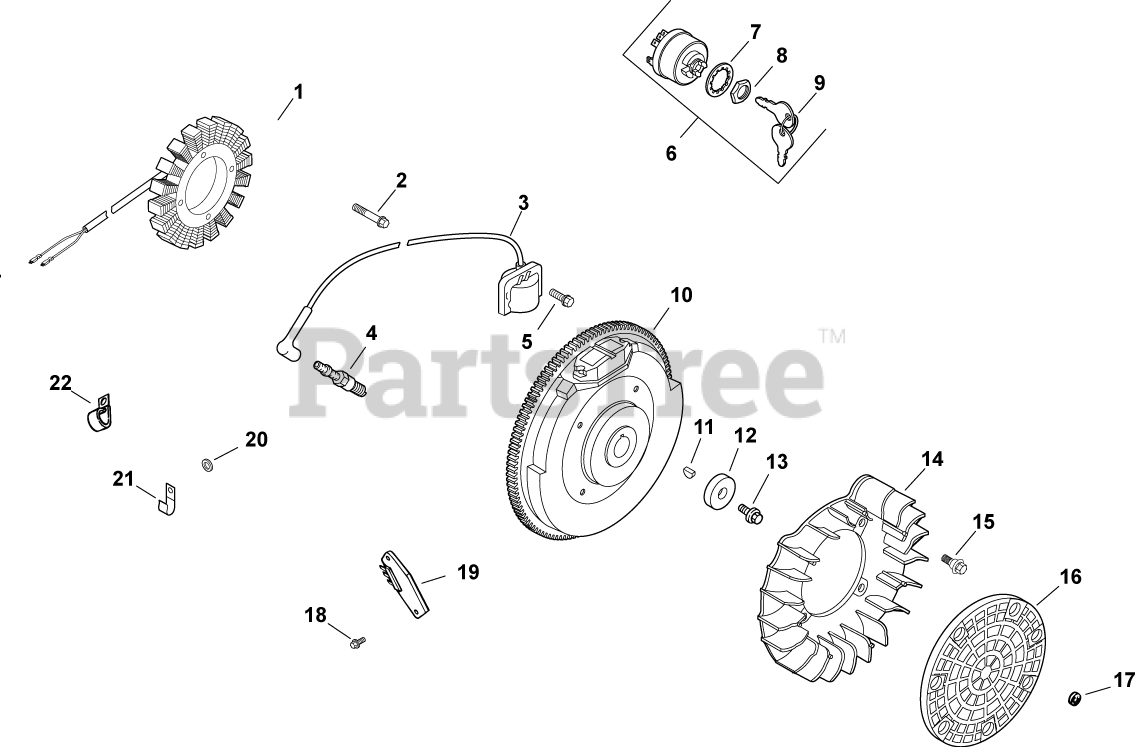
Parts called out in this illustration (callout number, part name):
1	KIT, 15 / 20 AMP STATOR
2	SCREW, M5X0.8X25 - (#25086402S)
3	KIT, MODULE IGNTN (CDI FIXED)
4	PLUG, SPARK (STD)
5	SCREW, FLG THD FRM M5X.8X20-(#25086399S)
6	SWITCH ASSY, KEY (KM)-USE 25 099 32-S
7	WASHER, INTERNAL TOOTH
8	NUT, KEY SWITCH
9	KEY, SET -USE 48 340 01-S
10	FLYWHEEL, PAINTED-USE 24 025 55-S
11	KEY, 3/16" X 5/8"
12	WASHER, FLAT 13/32"
13	SCREW, FLG M10X1.5X45 - (#25086361S)
14	FAN - USE (#24 157 11-S)
15	BOLT, SHOULDER
16	SCREEN, GRASS
18	SCREW, HEX FLANGE HI-LO
19	REG/RECT-15 AMP (KM)-USE 41 403 10-S
20	WASHER, FLAT 1/4" (O.D. 1/2")
21	CLIP, CABLE
22	CLIP, TUBE & WIRING (KM)
